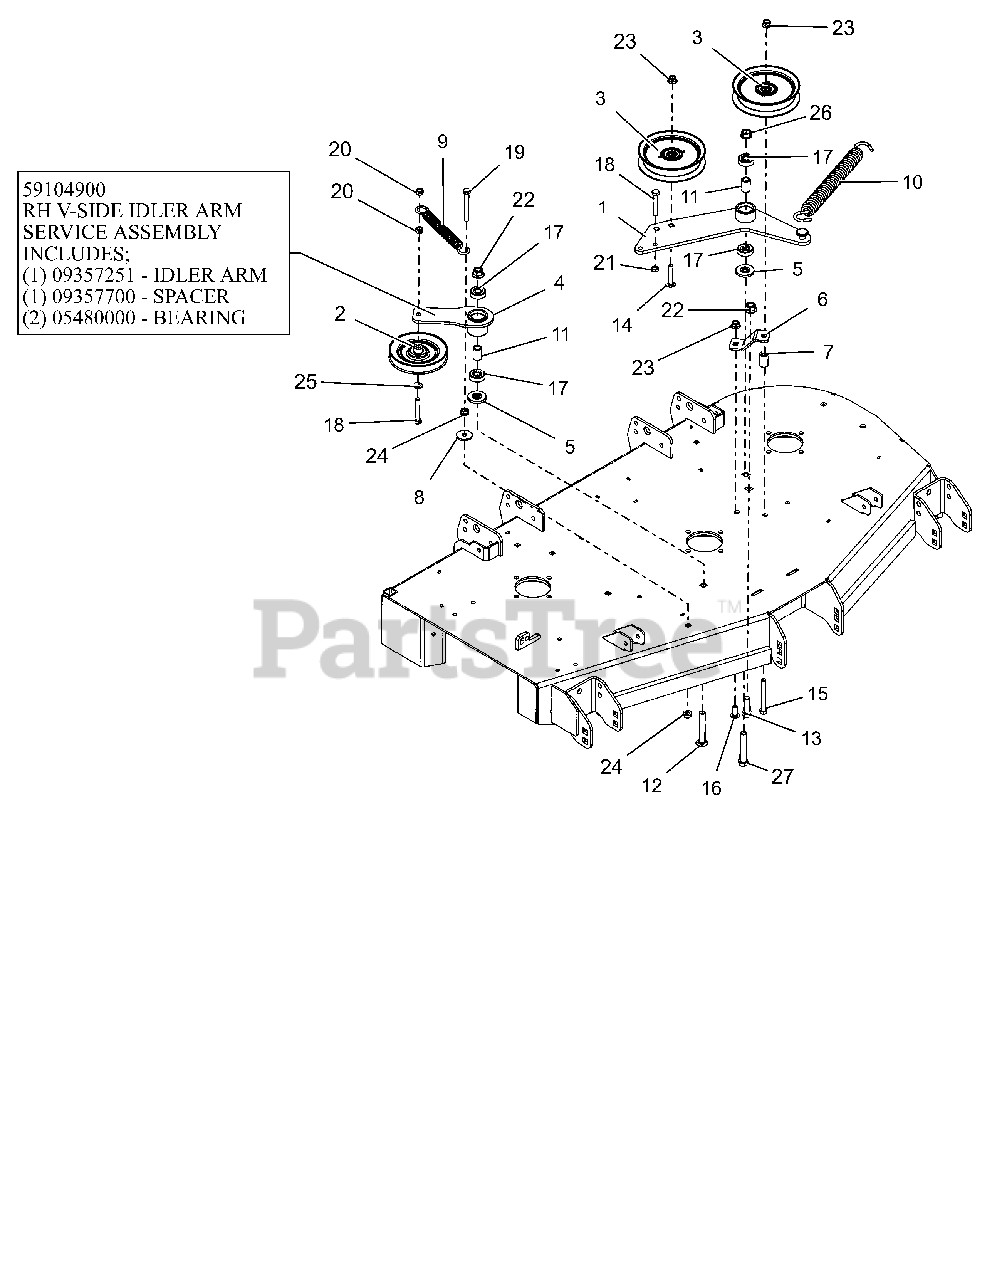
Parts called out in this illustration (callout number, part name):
1	DECK PTO IDLER ARM WLDMT - BLK
2	IDLER, V-5.00"
3	IDLER, FLAT 5.00"
4	DECK RH IDLER ARM WMT - BLK
4	RH V-SIDE IDLER ARM ASSEMBLY
5	SPACER, IDLER ARM
6	PTO FIXED IDLER MTG BRKT -RED
7	BUSHING, SLV .380X.750X1.190
8	WSHR-FL-STL .406X1.375X.135 YZ
9	SPRING, EXTENSION
10	SPRING, EXTENSION
11	SPACER .510 X .75 X 1.1485
12	BLT,RDHDSQSHNK.50-13X3.25 G5YZ
13	@BLT-HEX .50-13X1.50 GR5 YWZC
14	BLT-RDHDSQNK .38-16X2.00 SHTYW
15	@BLT-HEX .38-16X3.25 GR5 YWZC
16	@BLT-RDHDSHSQNK.38-16X1.0 G5YZ
17	BRG-BALL .500X1.38X.437
18	@BLT-HEX .38-16X2.25 GR5 YWZC
19	@BLT-HEX .38-16X3.00 GR5 YWZC
20	@NUT-LK-CTR .38-16 YWZC
21	NUT-HEX-JAM .375-16 YWZC
22	@NUT-LK-NYL-FLG .50-13 YWZC
23	@NUT-LK-NYL-FLG .38-16 YWZC
24	@NUT-SPNLK-FLG .375-16 YWZC
25	@WSHR-FL-STL.406X.812X.065 YWZ
26	NUT-LK-CTR-FLG .50-13 YWZC
27	@BLT-HEX .50-13X3.00 GR5 YWZC
